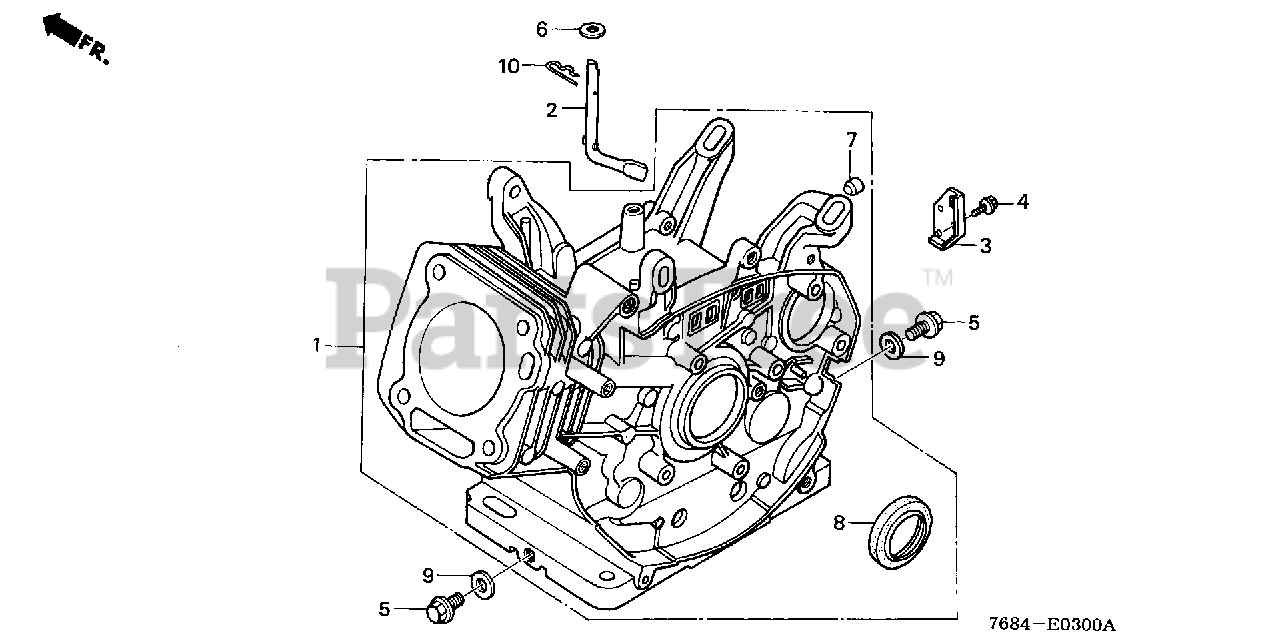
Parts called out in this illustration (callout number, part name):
1	CYLINDER ASSY. (STD)
2	SHAFT, GOVERNOR ARM
3	BASE, WIRE CLIP
4	BOLT, FLANGE (6X12) (CT200)
5	BOLT, DRAIN PLUG (12X15)
6	WASHER (8.2X17X0.8)
7	PLUG, SEALING (RUBBER 10MM)
8	OIL SEAL (30X46X8)
9	WASHER, DRAIN PLUG (12MM)
10	PIN, LOCK (10MM)
